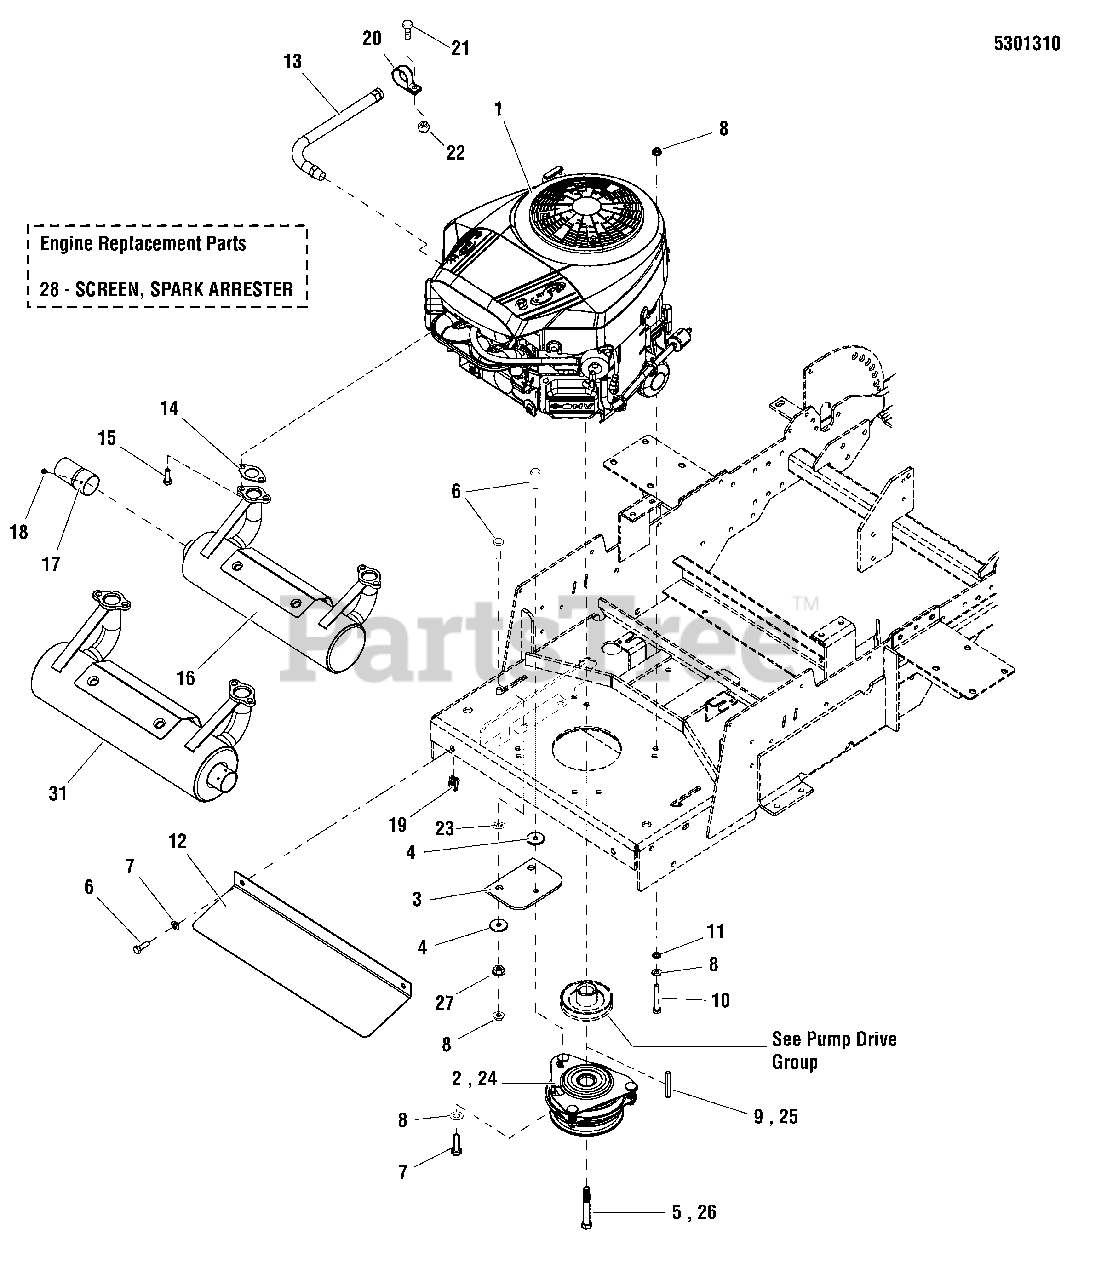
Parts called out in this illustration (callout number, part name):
2	CLUTCH, ELECTRIC, OGURA GT2.5, NZM
3	CLUTCH ANCHOR PAD
4	WASHER, .34 X 1.25 X 10 GA
5	BOLT, CRANKSHAFT, 7/16X2-3/4, PATCH YZ
6	BOLT, 5/16-18 X 1 GD5 YZ
7	WASHER, 5/16" SAE
8	NUT, 5/16-18 HEX NYLOCK FLANGE
9	KEY, 1/4" SQ. X 3.00
10	BOLT, 5/16-18 X 2-1/4" GD5 YZ
11	WASHER, 5/16" INT. TOOTH LOCK
12	PLATE, HEAT SHIELD - RED
13	HOSE, OIL DRAIN
14	* GASKET, EXHAUST
16	MUFFLER, B&S-ELS
17	EXTENSION, TAILPIPE, 3" - BLACK
18	SCREW
19	BODY CLIP, 5/16-18 X 1/2 DEEP
20	CLAMP, VINYL INSULATED
21	BOLT, 1/4-20 X 3/4 GD5 YZ
22	NUT, 1/4-20 HEX NYLON FLANGE
23	5/16" PUSH-ON NUT RETAINER, STL, CZ
24	CLUTCH, WARNER ELECTRIC, I-5219-104
25	KEY, 1/4 SQ. X 1.00
26	BOLT, 5/16-18 X 2 GD5 TFL
27	NUT, 5/16-18 HEX SERRATED FLANGE (LARGE)
28	SCREEN, SPARK ARRESTER
31	MUFFLER, RIGHT OUTLET ASSY
